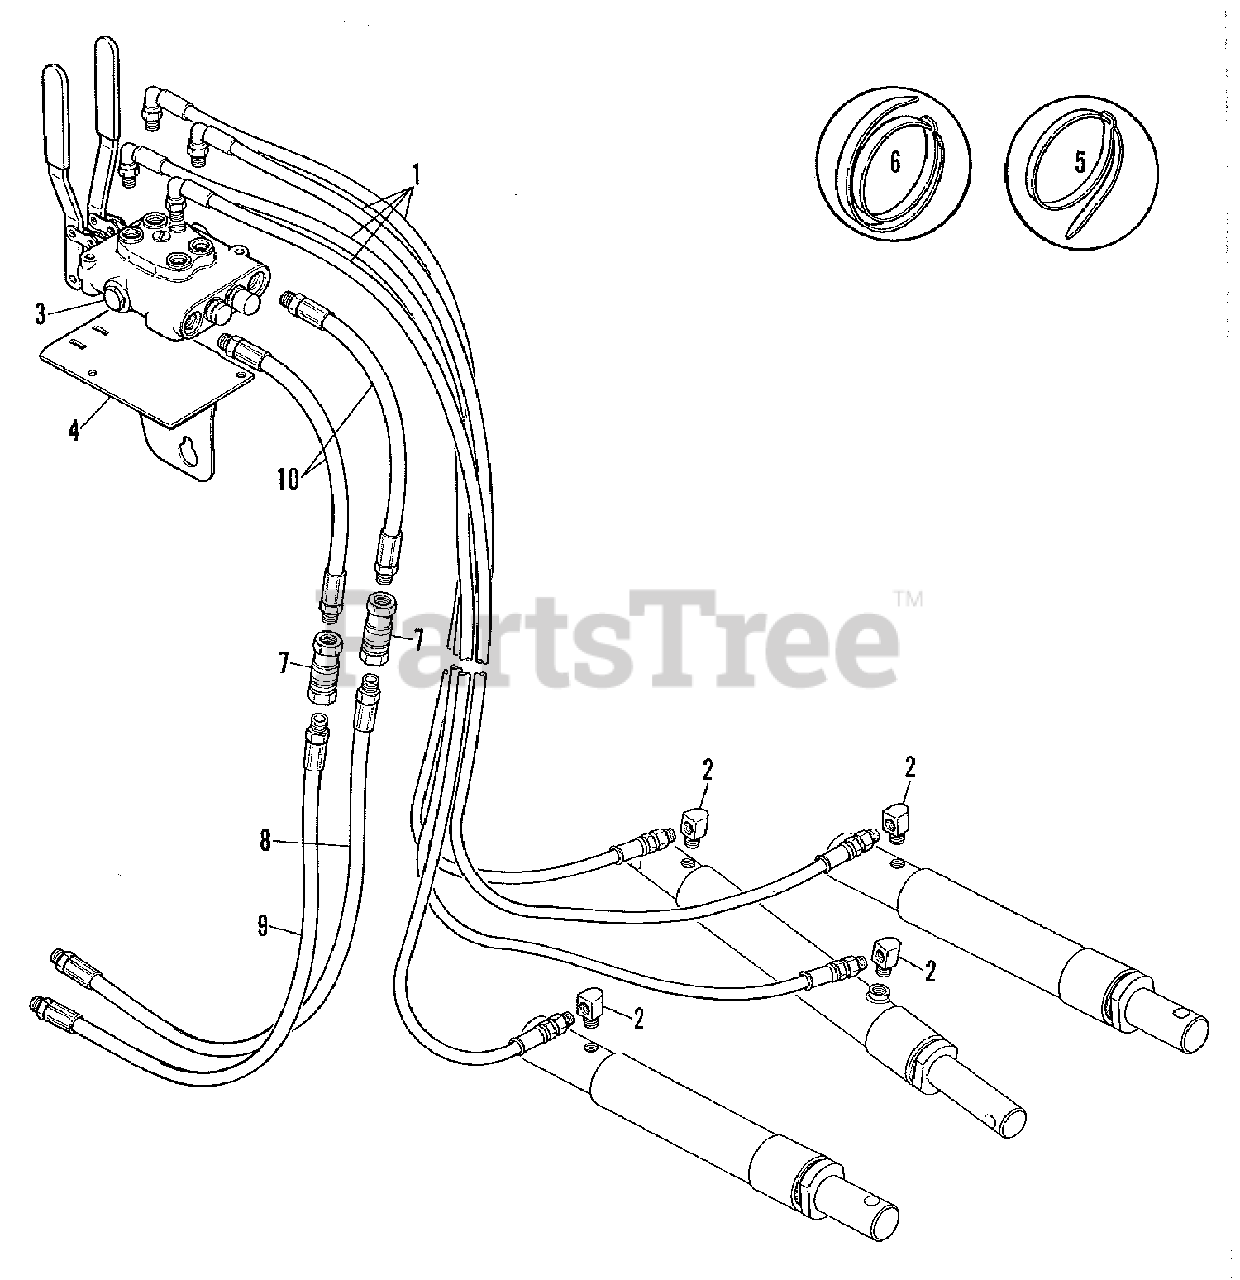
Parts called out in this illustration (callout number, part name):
1	HOSE ASSEMBLY
2	ELBOW, Street, 90 Degrees
3	VALVE, Control
3	CAPSCREW, 1/4NC x 2
3	LOCKWASHER, 1/4
4	BRACKET, Valve Mounting
4	CAPSCREW, 8mm x 25mm
4	LOCKWASHER, 5/16
4	WASHER, Plain
5	TIE, Plastic
6	TIE, Plastic
7	COUPLER, Hose
8	HOSE ASSEMBLY (Selector Valve to Control)
9	HOSE ASSEMBLY (Control to Manifold)
10	HOSE ASSEMBLY (Valve Inlet & Outlet)
